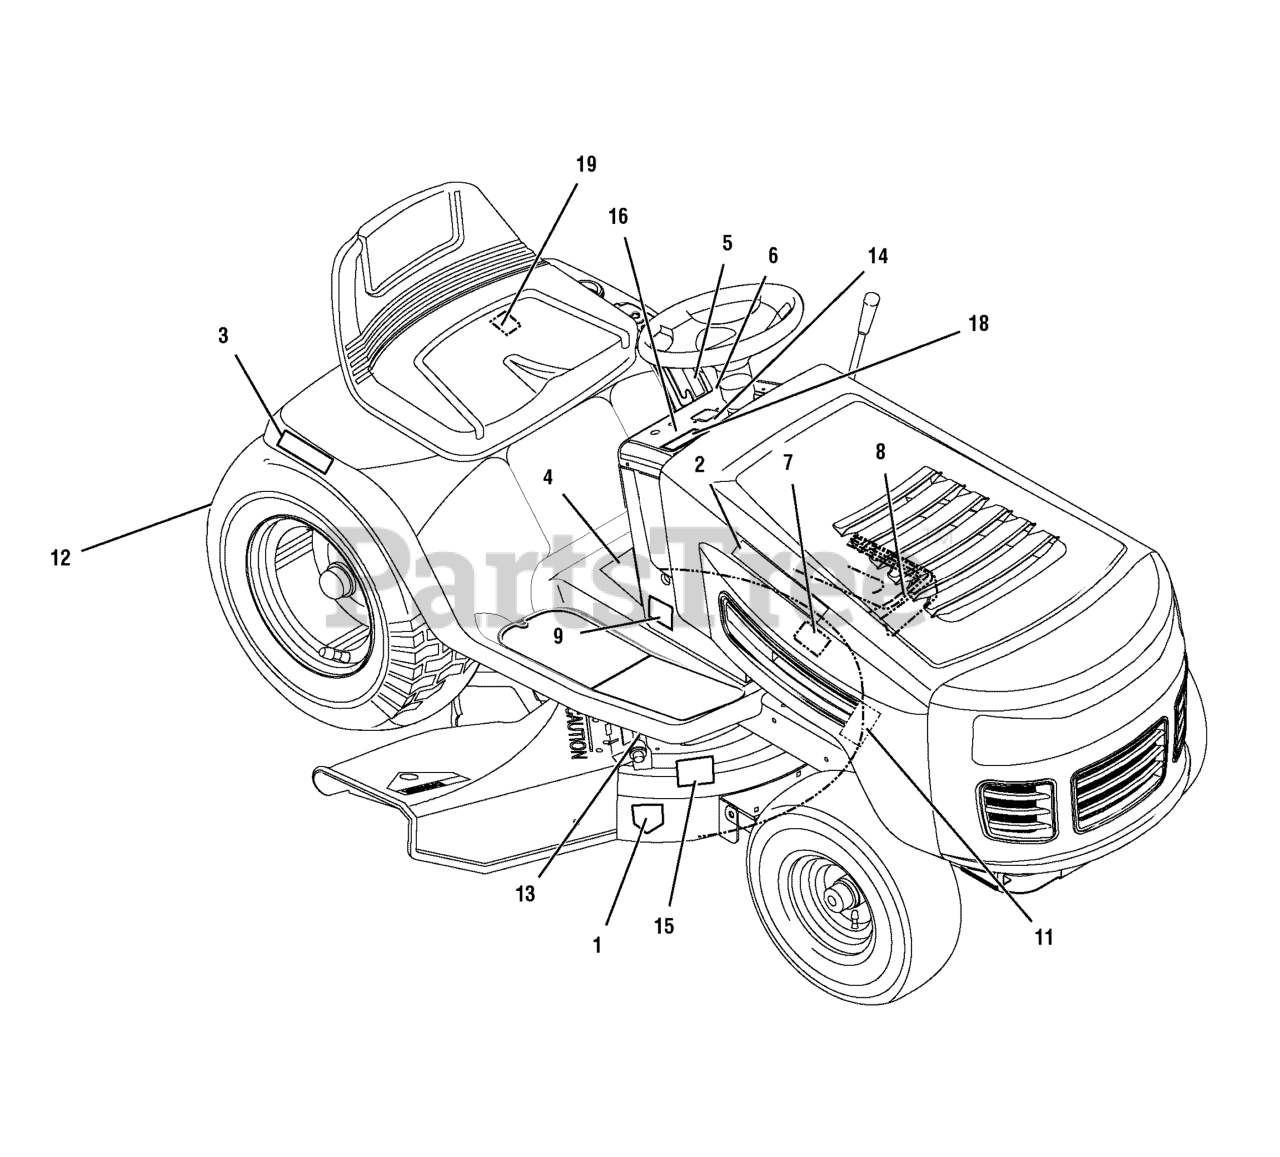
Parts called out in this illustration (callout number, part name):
1	DECAL, Cut Finger Symbols
2	DECAL, Murray R.H. & L.H.
3	DECAL, 135/102 R.H. & L.H.
4	DECAL, Warning Export
5	DECAL, 7 Position Cut Height
6	DECAL, Deck Level
7	DECAL, No Step Export
8	DECAL, Brake/Clutch Export
9	DECAL, B&S Logo
11	DECAL, Heat Shield Warning
12	DECAL, Warning Load Limit Export
13	DECAL, Warning Pinch Point
14	DECAL, Dash/Symbols X-W Styles
15	DECAL, 100db Export
16	DECAL, Gas Gauge
18	DECAL, Hydro Drive
19	DECAL, Auto Drive Dump Valve
